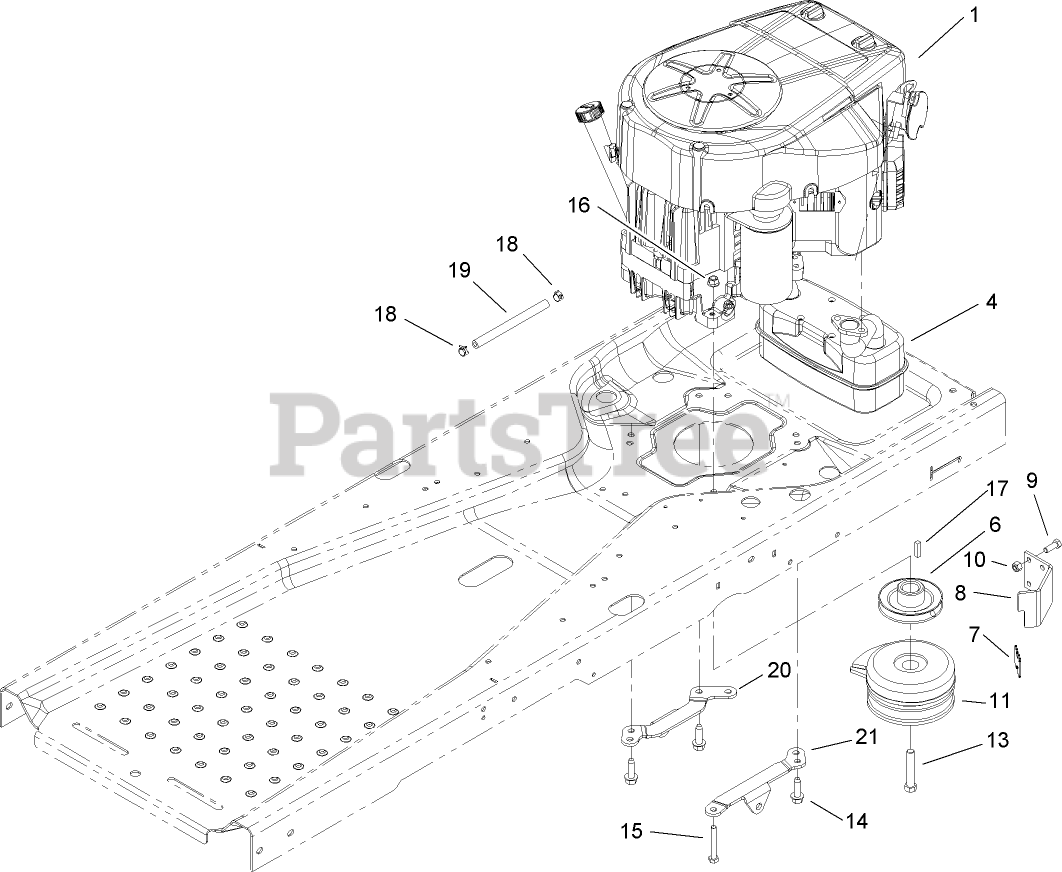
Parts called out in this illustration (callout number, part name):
1	Loose Parts Package
8	STOP-CLUTCH
9	SCREW-HH
10	NUT-LOCK, NI
11	CLUTCH-ELECTRIC, PTO
13	SCREW-HH
14	SCREW-THD
15	SCREW-HH
16	NUT-LOCK, NI
18	CLAMP-HOSE
19	HOSE-FUEL
20	SUPPORT-HYDRO, RH
21	SUPPORT-HYDRO, LH
